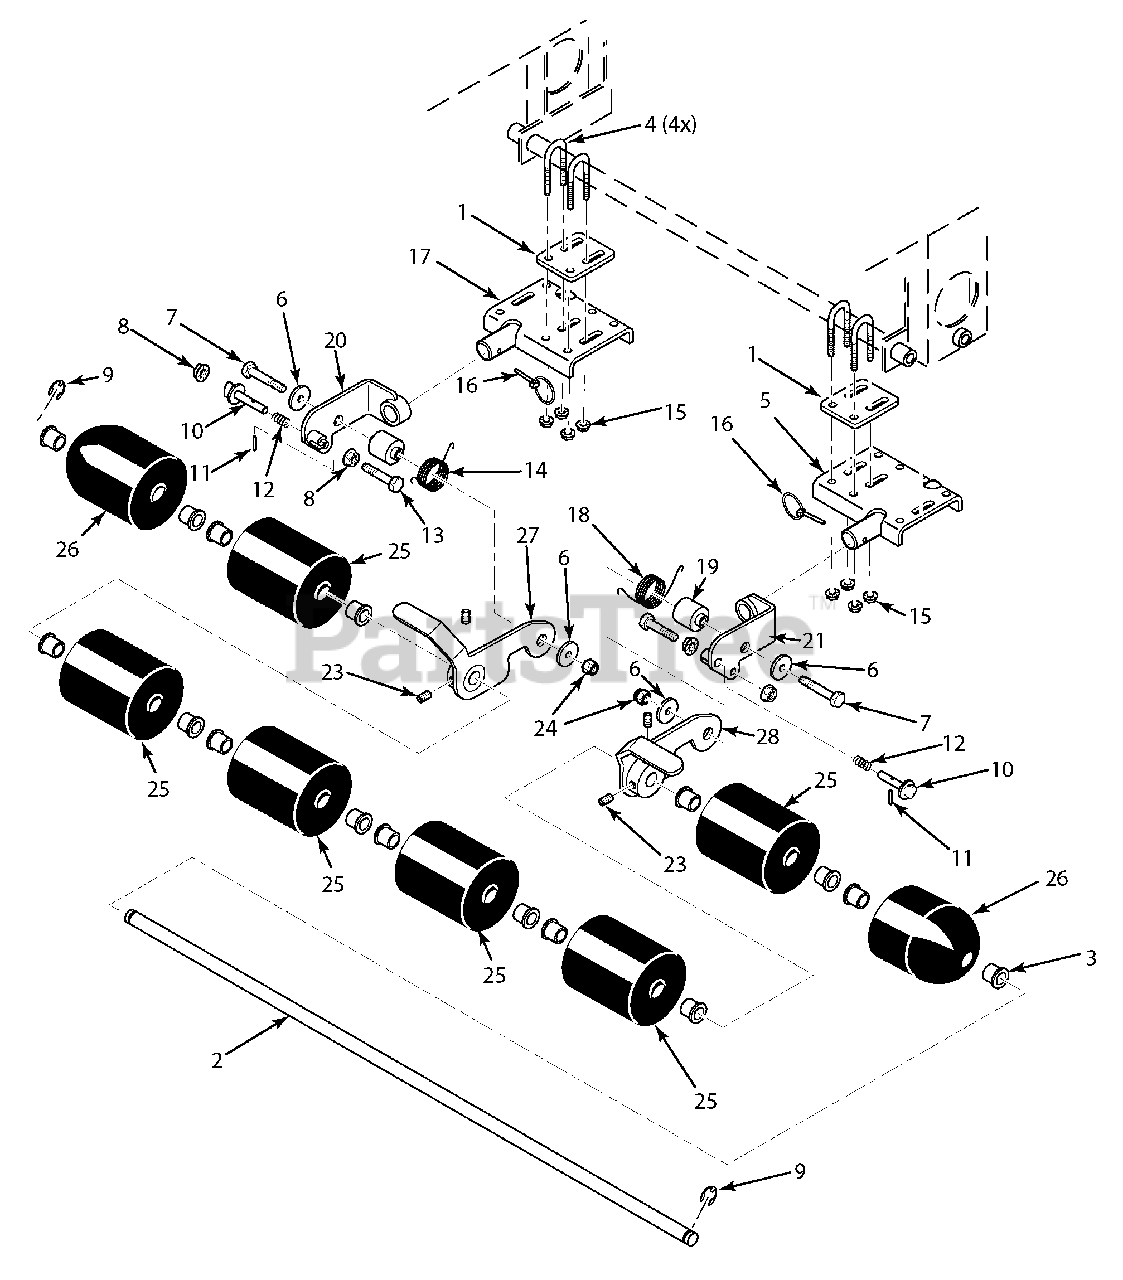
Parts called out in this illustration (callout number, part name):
1	Spacer, Striper Mounting
2	Roller Shaft
3	Bushing, .752 Oilite
4	U-Bolt, 5/16-18 x 1"
5	Mounting Bracket Weldment, LH.
6	Flatwasher, 3/8-.406 x 1-1/2" 7 Gauge
7	Bolt, Hex Head 3/8-16 x 2-3/4"
8	Nut, Serrated Flange 3/8-16
9	Retaining Ring, .750 External "E"
10	Pin, Lift Latch
11	Pin, Slotted Spring .156 x 3/4"
12	Spring, Lock Pin
13	Bolt, Hex Head 3/8-16 x 2-1/2"
14	Spring, Torsion L.H.
15	Nut, Serrated Flange 5/16-18
16	Quick Pin, .188 Dia.
17	Mounting Bracket Weldment, R.H.
18	Spring, Torsion R.H.
19	Hub, Striper
20	Pivot Weldment, L.H.
21	Pivot Weldment, R.H.
22	Hinge Weldment, R.H.
23	Set Screw, 3/8-16 x 1/2"
24	Nut, Elastic Stop 3/8-16
25	Roller Assembly
26	Roller Assembly, Striper End
27	Hinge Weldment, L.H.
